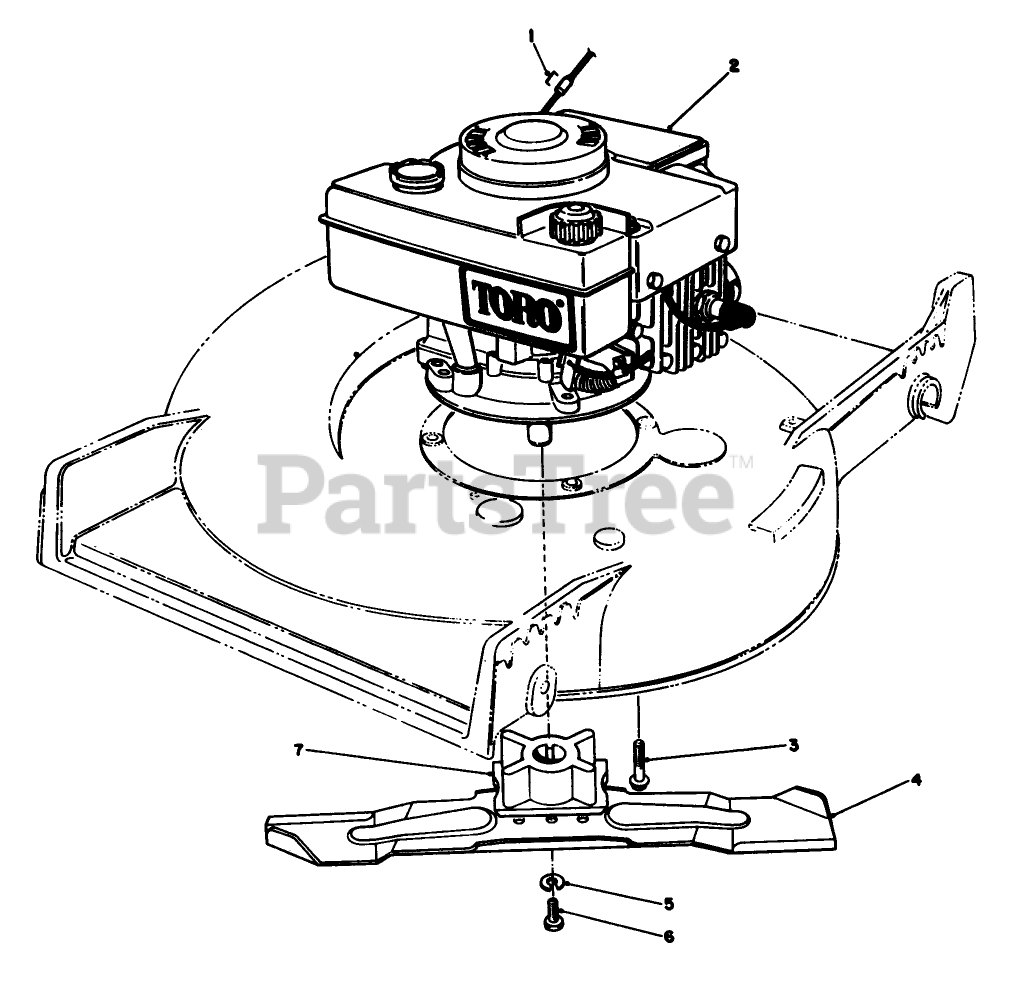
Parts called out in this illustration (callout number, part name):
1	Staple
2	Engine
3	3/8-16 X 2 CAPSCREW
5	WASHER-LOCK
6	SCREW-BLADE
7	Retainer-Blade
